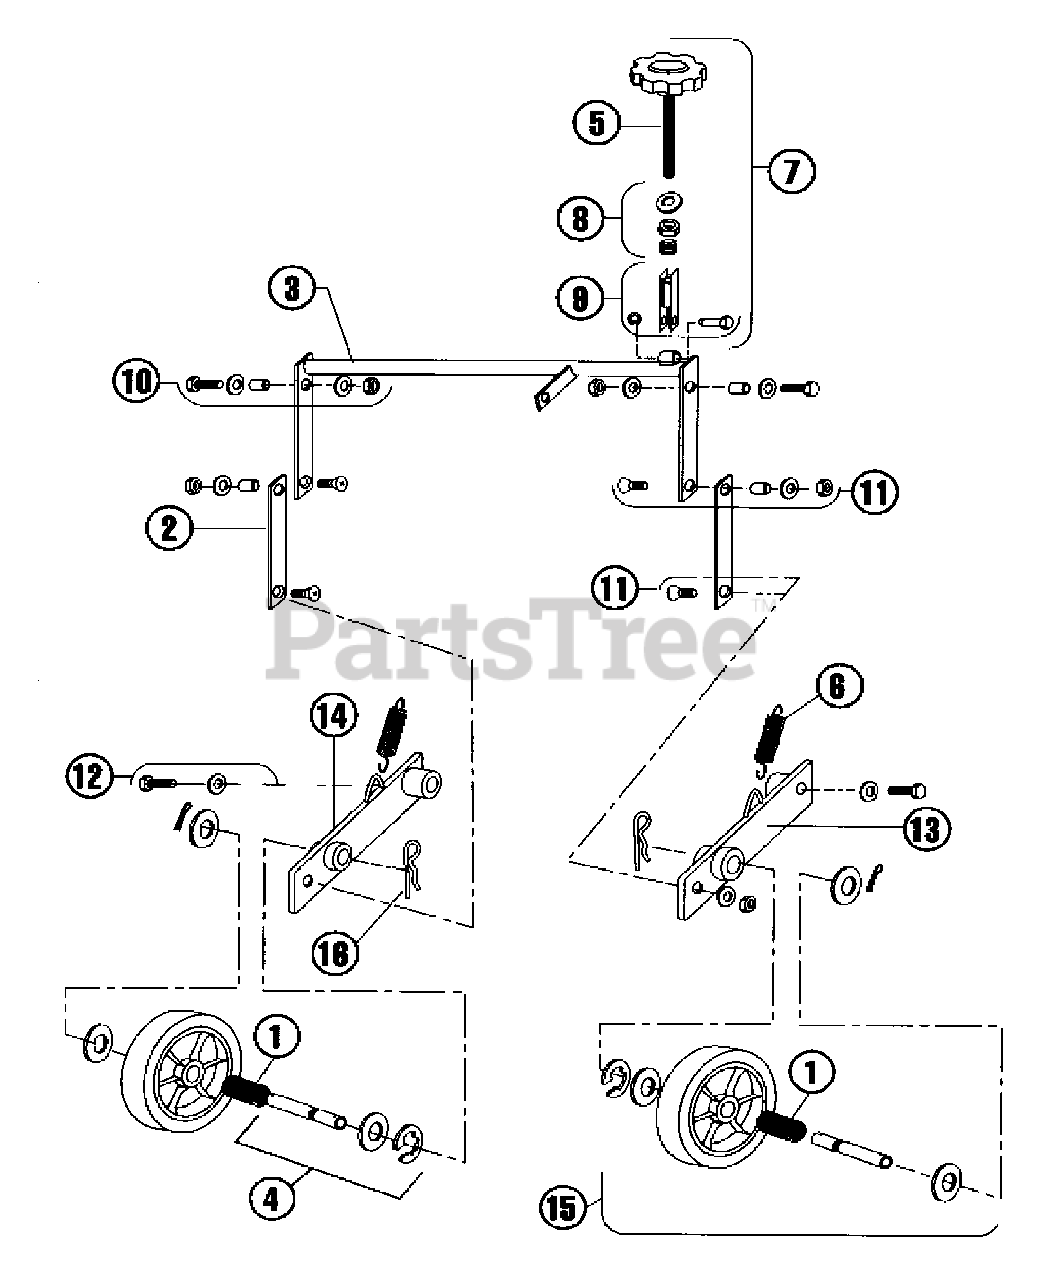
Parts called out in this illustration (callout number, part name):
1	Bearing, roller with seals
3	Torque arm, depth adjustment
4	Axle kit, axle, E-clip, 2 washers, cotter pin, hairpin cotter
5	Knob, depth/stability
6	Spring, axle
7	Control kit, depth/stability
8	Knob spring kit, depth/stability
9	Bracket kit, depth/stability
10	Fastener kit, torque arm/housing
11	Fastener kit, linkage
12	Fastener kit carriage/housing
13	Wheel arm right
14	Wheel arm left
15	Wheel assembly wheel, bearing, 2 seals, axle, 2 washers, E-clip, cotter pin, hairpin cotter
16	Cotter key, hairpin
